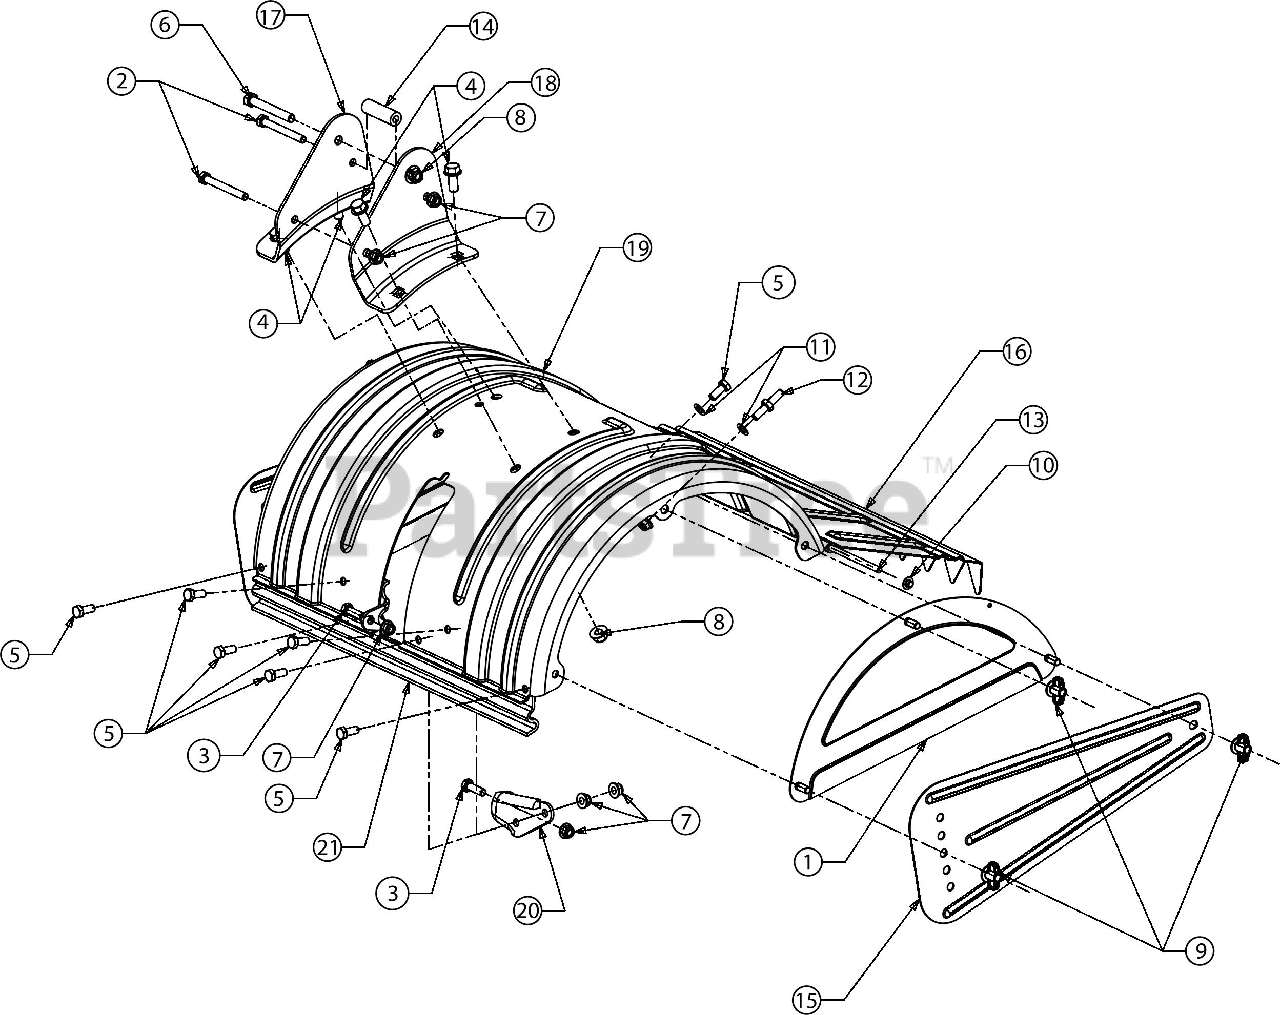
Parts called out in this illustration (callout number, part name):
2	HEX SCREW 5/16-18 X 2.75
3	SCREW 5/16-18 X 1.0 GR5
4	SCREW 3/8-16 X .875 GR5
5	SCREW 5/16-18 x .75 GR5
6	SCREW 3/8-16 X 2.75 GR5
7	FLANGE LOCK NUT 5/16-18
9	WING NUT 5/16-18
10	PUSH NUT
11	FLAT WASHER .344 ID X .62 OD X .033
12	SHOULDER SCREW
13	TILLER FLAP ROD
20	TINE SHIELD BRACKET
21	SHOULDER SPACER BRACKET
